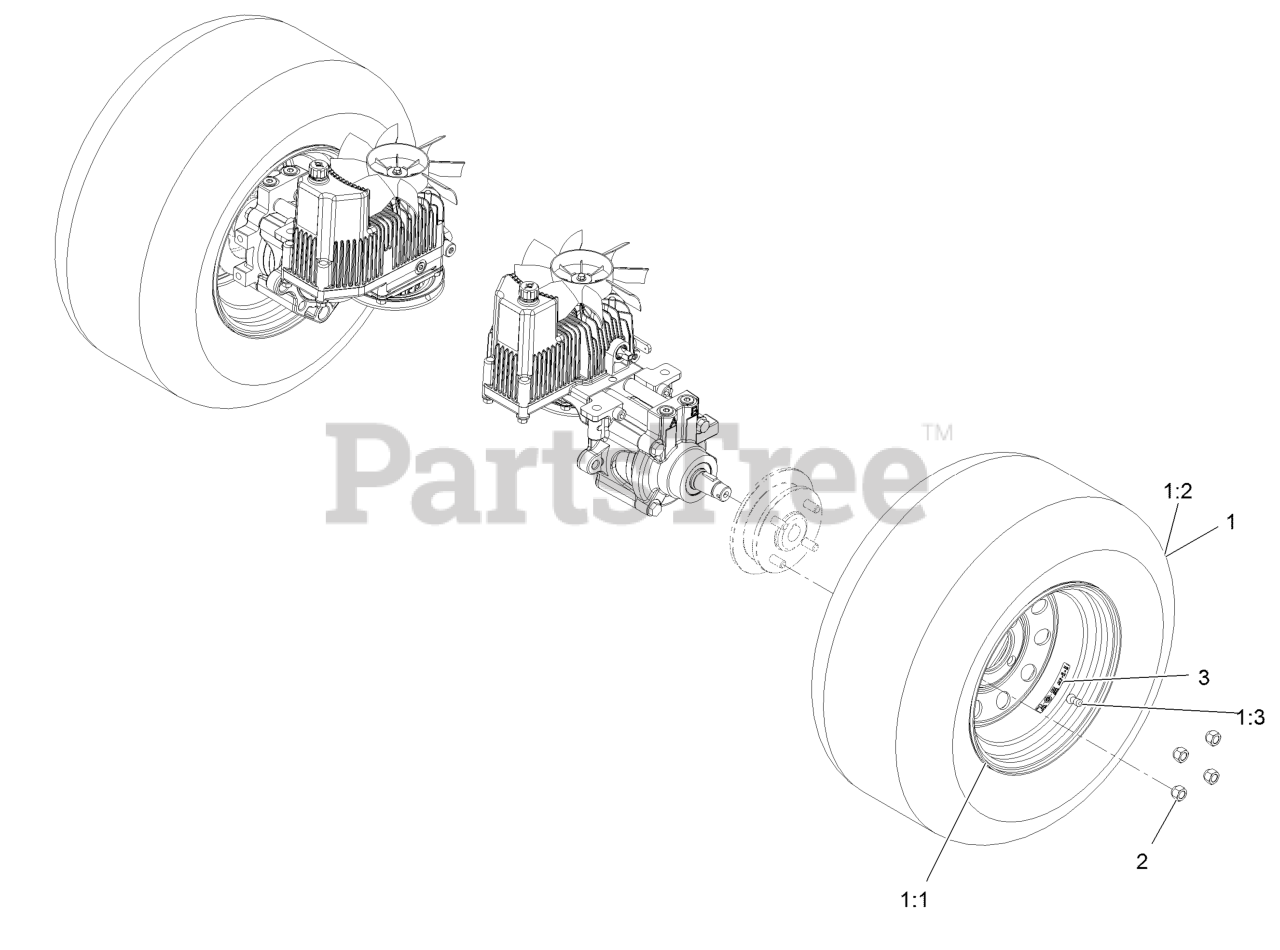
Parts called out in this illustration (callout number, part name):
1	ASM-WHEEL AND TIRE
1:1	ASM-RIM 60
1:2	TIRE-DRIVE
1:3	Stem-Valve
2	NUT-LUG
3	DECAL-TORQUE, WHEEL HUB LUG
